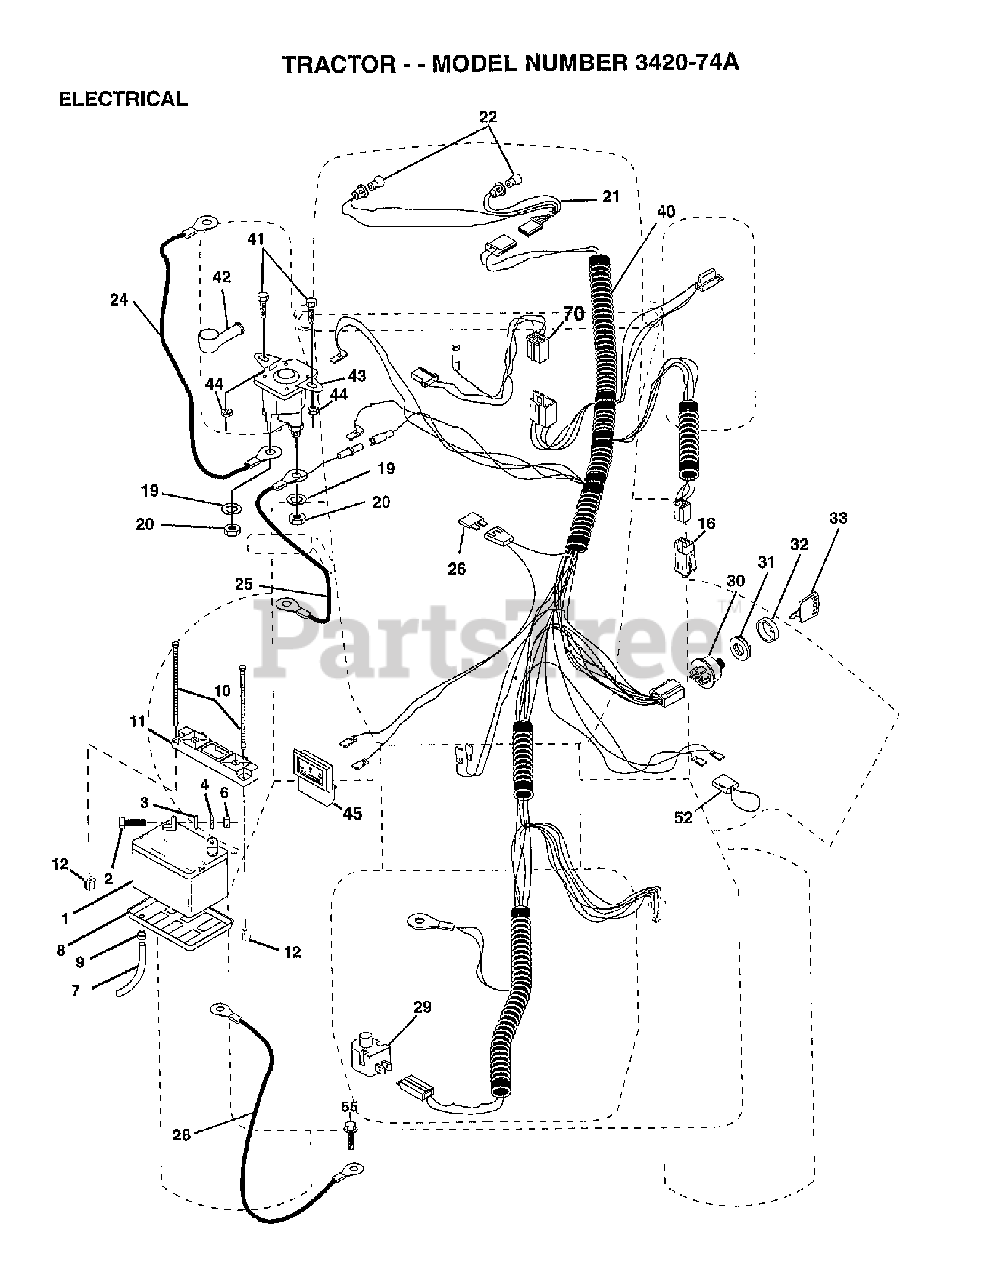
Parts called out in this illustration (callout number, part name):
2	BOLT.HEX.1/4.X.3/4.DICHROMATE
3	WASHER
4	LOCKWASHER
6	NUT
7	BATT DRAIN TUBE T
8	TRAY.BATTERY
9	HOSE CLAMP T
10	BOLT 1/4-20 X 7.5
11	BATTERY HOLDDOWN
20	NUT
22	LIGHTBULB
24	BATTERY CABLE
25	CABLE BATTERY 6 GA 22" W/16W
26	FUSE *
28	CABLE GROUND 6 GA 21" 90T BLK
29	SWITCH SEAT
30	SWITCH.IGNITION.4.POSITION
31	NUT
32	COVER KEY IGNITIO
33	KEY.MOLDED.GENERIC
41	BOLT
42	TERMINAL COVER
43	Solenoid Kit, .95
44	NUT.HEX.KEPS.1/4-20
45	AMMETER
52	WIRE PROTECTION LOOP
55	SCREW LT
70	HARNESS, ENGINE
